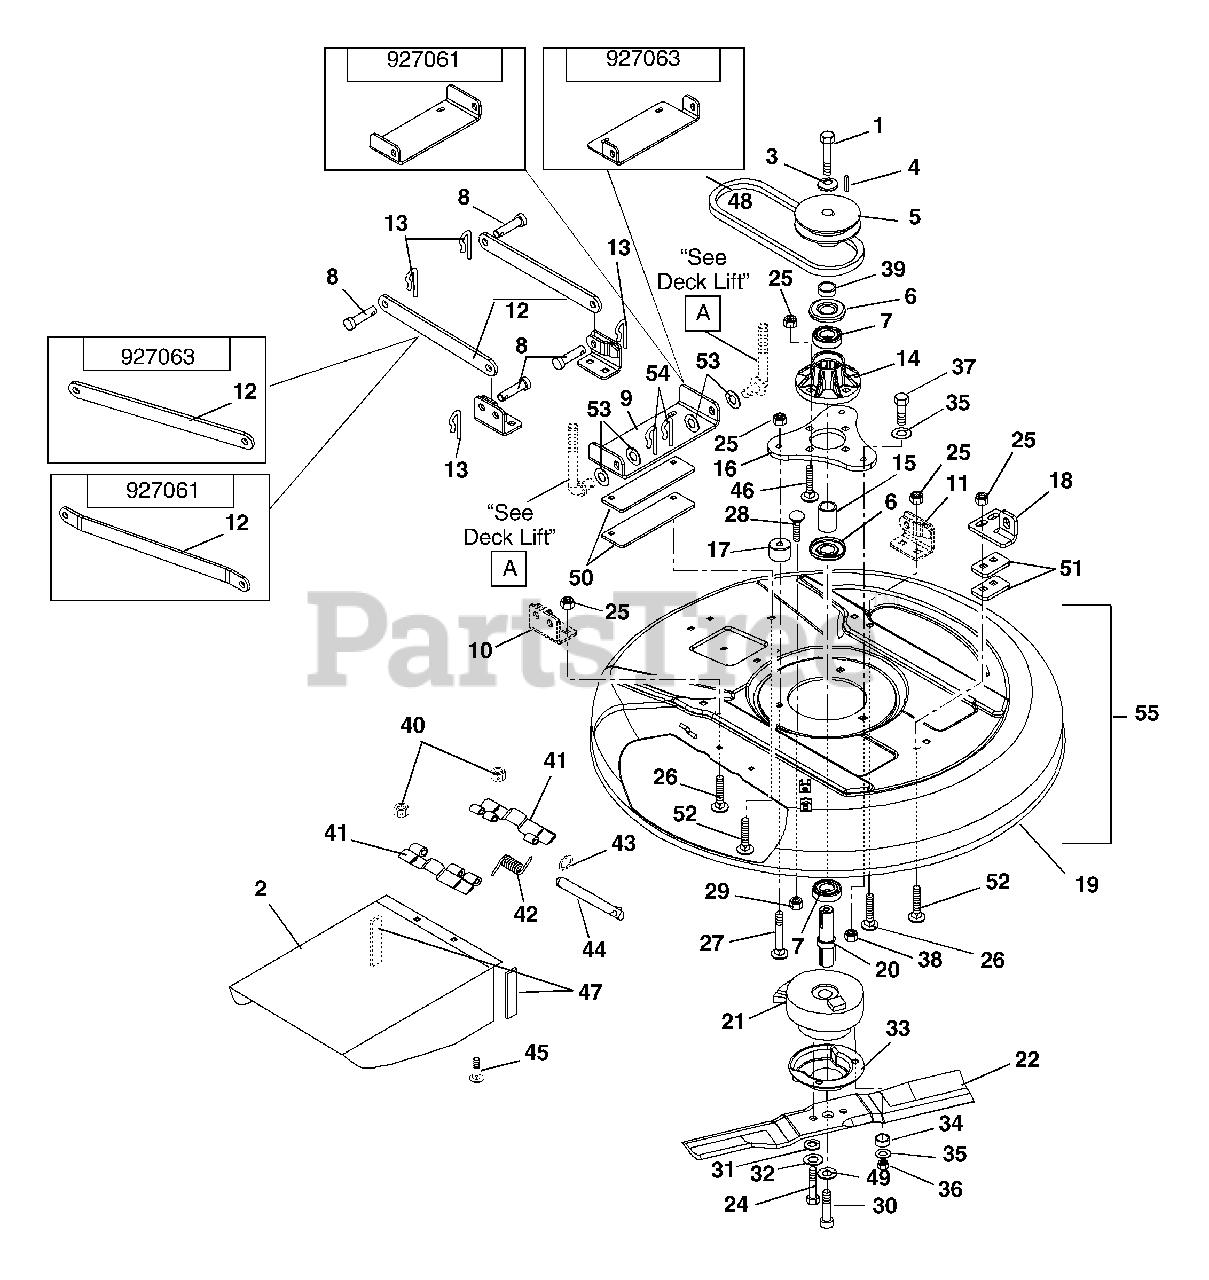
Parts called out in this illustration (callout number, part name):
1	BLT-HEX .38-16X1.00 YZ GR8
2	CHUTE-28" DECK
2	CHUTE-32" DECK
3	WASHER, CUPPED SERRATED, .375
4	KEY, SQ .25 X .38 X .25
5	PULLEY, 28" DECK INPUT
5	SHEAVE, 4.25 DIA A-SECTION
5	PULLEY, 32" DECK INPUT
5	SHEAVE, 4.75 DIA A-SECTION
6	BEARING SLINGER
7	BRG-BALL 1.0X2.0X.56 (1641)
8	PIN-CLEV .494X1.00 BLKZC
9	BRKT, REAR HANGER (28" DECK)
9	BRKT, FRONT LIFT (32" DECK)
10	BKT-DECK LINK RH
10	WLDMT-DECK LINK (RH)
11	WLDMT-DECK LINK (RH)
11	WLDMT-DECK LINK (LH)
12	STABILIZER LINK 28"
12	LINK STABILIZER 32"
13	CLIP, SPRING
14	ASSY-SPINDLE HSG
15	SPACER, 1.001 X 1.25 X 1.76
16	SPINDLE MOUNT PLATE
17	SPACER-MOUNTING PLATE
18	BRKT, FRONT HANGER (28" DECK)
18	BRKT, FRONT LIFT (32" DECK)
19	WLDMT-28" DECK RER
19	WLDMT-32" DECK
20	SHAFT, 28" AND 32" INPUT
21	KIT, CLUTCH (1028 RER)
21	KIT, CLUTCH (1232 RER)
22	BLADE-CUTTING 28"
23	BLADE, 32" RER/ZS
24	BLT-HEX M10X1.25X30 CLS 10.9
25	NUT-LK-TOP-FLG .38-16 BLKZC
26	BLT-RDHDSQNK .38-16X.75 G5BZ
27	BLT-RDHDSQNK .38-16X2.25 G5BZ
28	@BLT-RDHDSQNK .31-18X1.50 G5YZ
29	@NUT-SPNLK-FLG .312-18 YWZC
30	SCR-SKN .5-20X1.25 BTNHD
31	WSHR-LK M 10MM YZ
32	WSHR-FL-STL .406X1.00X.188 YWZ
33	SHIELD, DEBRIS
34	BSHG, SPCR .752X.877X.50 BRZ
35	@WSHR-FL-STL.38X.875X.083 YWZC
36	@NUT-LK-NYL .38-16 YWZC
37	BLT-HEX .38-16X3.00 GR5 FTH YZ
38	@NUT-SPNLK-FLG .375-16 YWZC
39	SPACER 1.008X1.377X.509 ST
40	NUT-LK-FLG .250-20 PL BLK
41	HINGE PLATE
42	SG-TORS .090X.37X.63
43	RG-RTNG-EXT .312X.025
45	@BLT-RDHDSQNK .25-20X.75 G5YZ
46	@BLT-RDHDSQNK .38-16X1.25 G5YZ
47	TRIM BULK
48	KIT, 28" CUTTING IMPROVEMENT
48	V-BELT, HA-WRAPPED
48	KIT, 32" CUTTING IMPROVEMENT
48	V-BELT HA, 62.1
49	WASHER, FLT STL .5X1.75X.187
50	PLATE, 32" REAR HANGER SPACER
51	PLATE, 32" FRONT HANGER SPCR
52	@BLT-RDHDSQNK .38-16X1.25 BKZC
53	WSHR-FL-STL .518X2.0X.105 YWZC
54	PIN, HAIR, EXT - #16 YWZC
55	KIT, 28" DECK ASSY SERVICE
55	KIT, 32" DECK ASSY SERVICE
